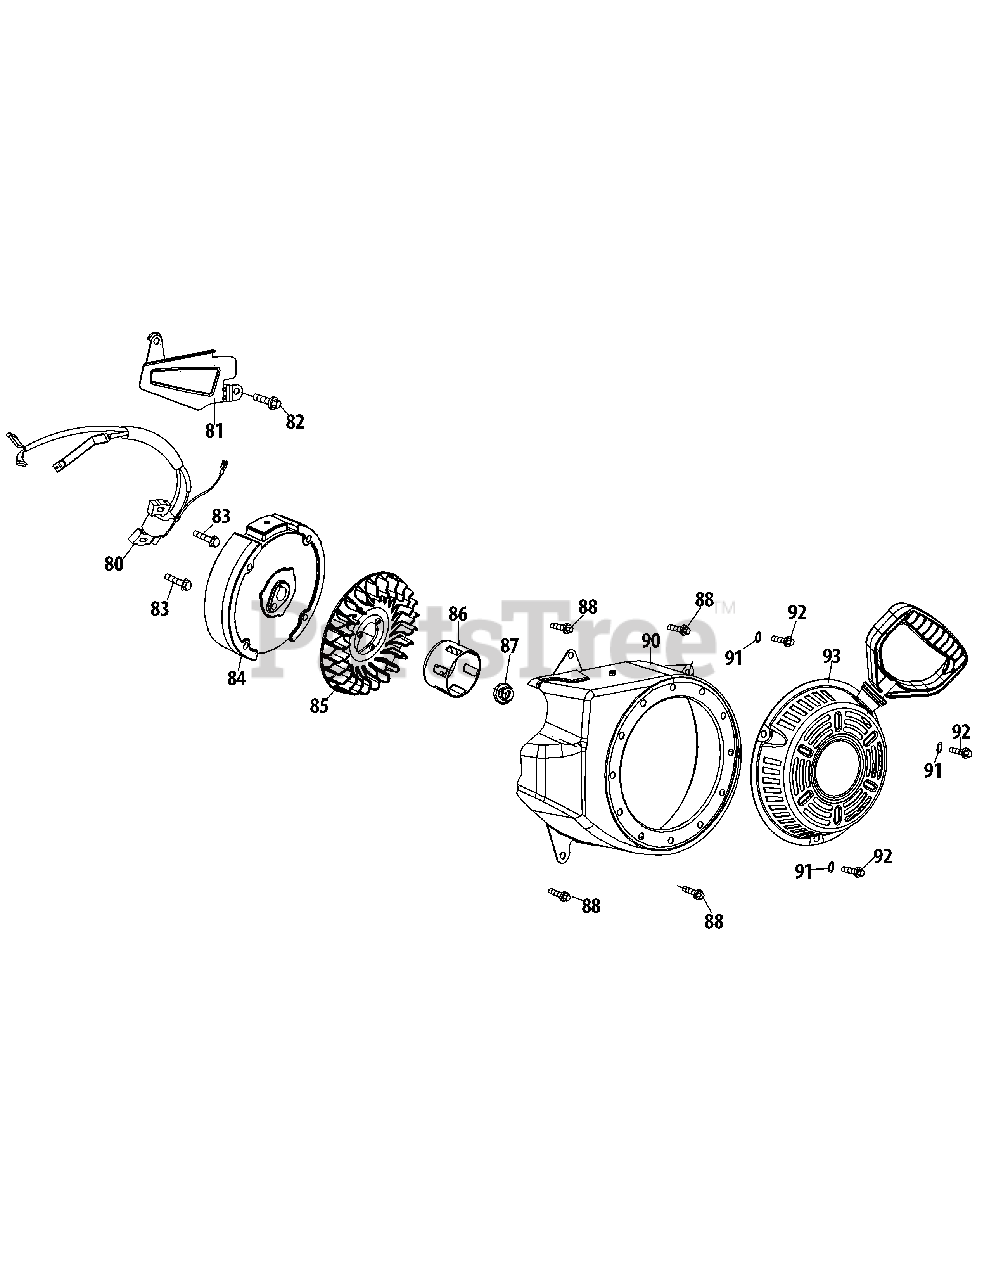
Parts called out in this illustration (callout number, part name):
80	Ignition Coil Assembly
81	Air Flow Shield
82	Bolt M6×10
83	Bolt M6×25
84	Flywheel
85	Fan, Cooling
86	Pulley, Starter
87	Nut, Special, M14×1.5
88	Bolt M6×12
90	Blower Housing
91	Gasket 6
92	Bolt M6×10
93	Recoil Starter
93	Recoil Starter Handle
